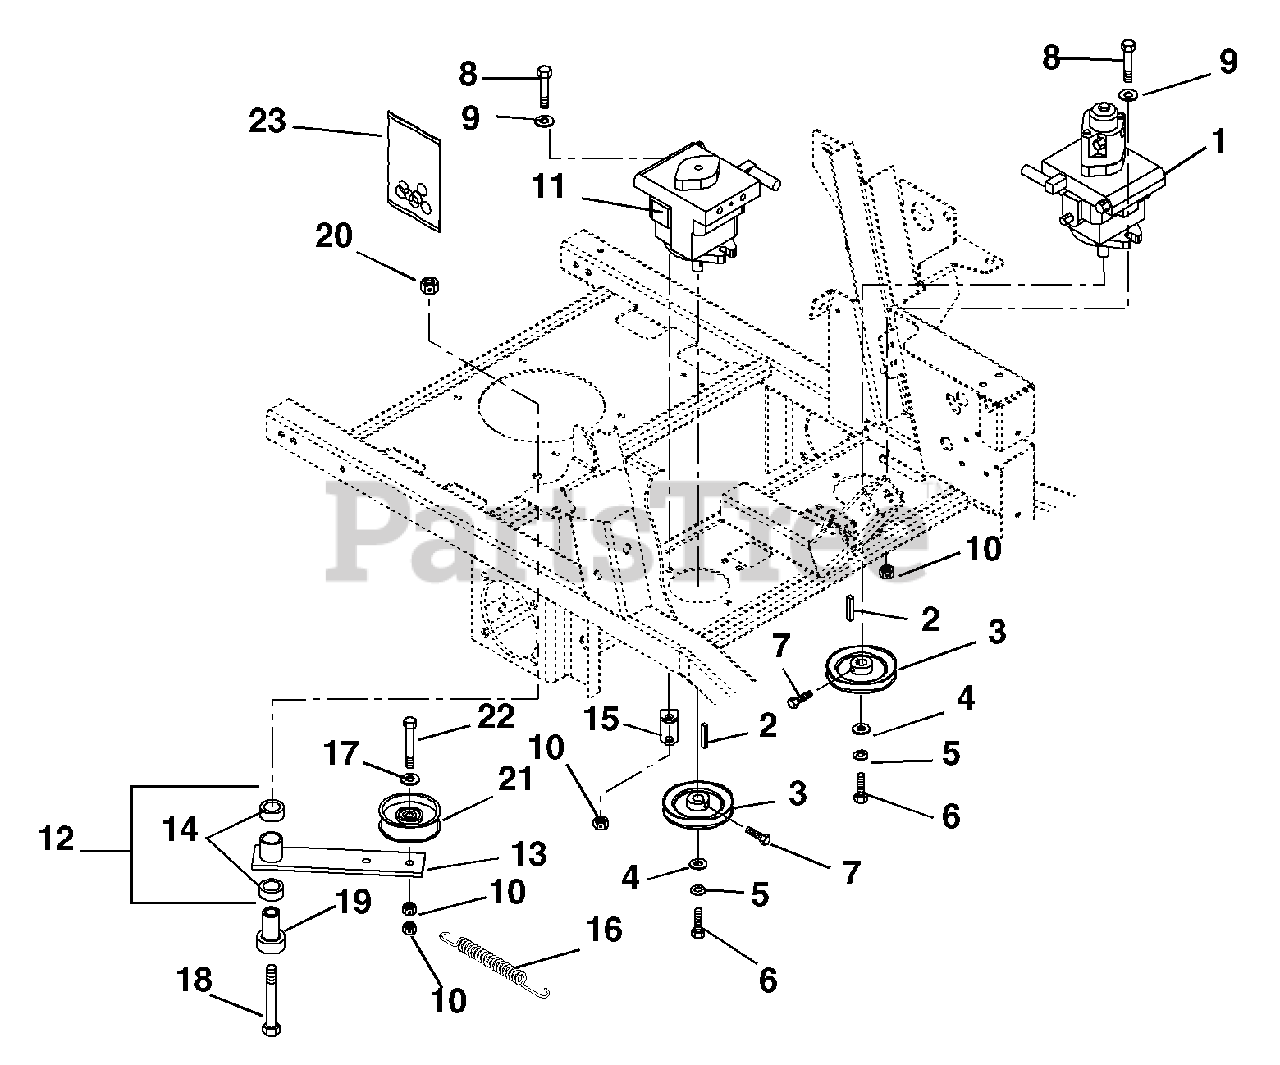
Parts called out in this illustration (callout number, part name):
1	Hydrostat BDP with Auxiliary
2	Key-Straight 5mm x 25mm x 5mm
3	Sheave 4.0 x .199
4	Washer-Flat-Steel .25 x 1.0 x .048
5	Washer-Locking .25 x .062
6	Bolt-Hex M6 x 1.0 x 12
7	Bolt-Hex .25-20 x .50 Grade 5
8	Bolt-Hex .38-16 x 1.25 Grade 5
9	Washer-Flat-Steel .390 x .75 x .125
10	Nut-Locking-Center .38-16
11	Variable-Displace Pump
12	Assembly,Idler Arm Guard Drive
13	Weldment, Idler Arm Ground Drive
14	Bearing, 1.00 x 1.12 x .75
15	Anchor-Spring-Idler
16	Spring-Tension .120 x .845 x 6.500
17	Washer-Flat-Steel .39 x.75 x.125
18	Bolt-Hex .50-13 x 3.50 Grade 5
19	Bearing, Pedestal Powdered Metal
20	Nut-Locking-Center .50-13
21	Assembly-Idler Pulley
22	Bolt-Hex .38-16 x 2.25 Grade 5
23	Kit-Pump Seal
24	Fan, Cooling
